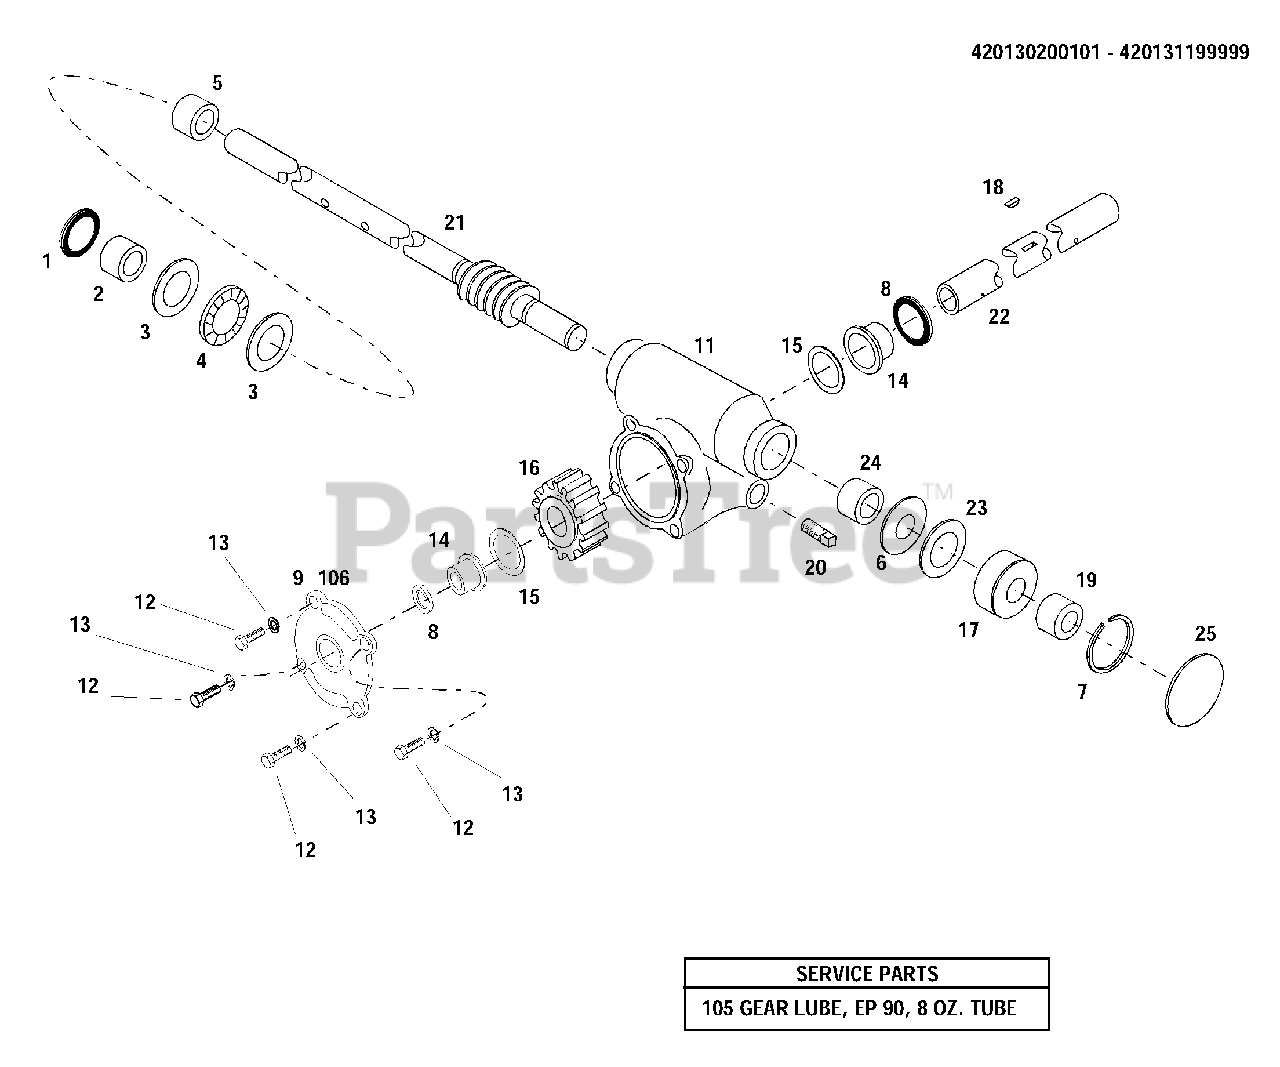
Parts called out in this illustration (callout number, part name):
2	Needle Bearing
3	Thrust Race
4	Thrust Bearing
6	Washer
7	Internal Retaining Ring
8	Oil Seal
9	Gear Case Cover
11	Gear Case Housing
12	Bolt, 1/4-20 x 5/8
13	Lockwasher, 1/4
14	Flange Bearing
15	Thrust Race -
16	Worm Gear, 20T
17	Spacer
18	Woodruff Key, 1/4 x 7/8
19	Needle Bearing
20	Pipe Plug, lw-a
21	Impeller Shaft
22	Auger Shaft
23	Thrust Race
24	Spacer
25	Welsh Plug
105	Gear Lube, EP 90, 8 oz. Tube
106	Sealant
